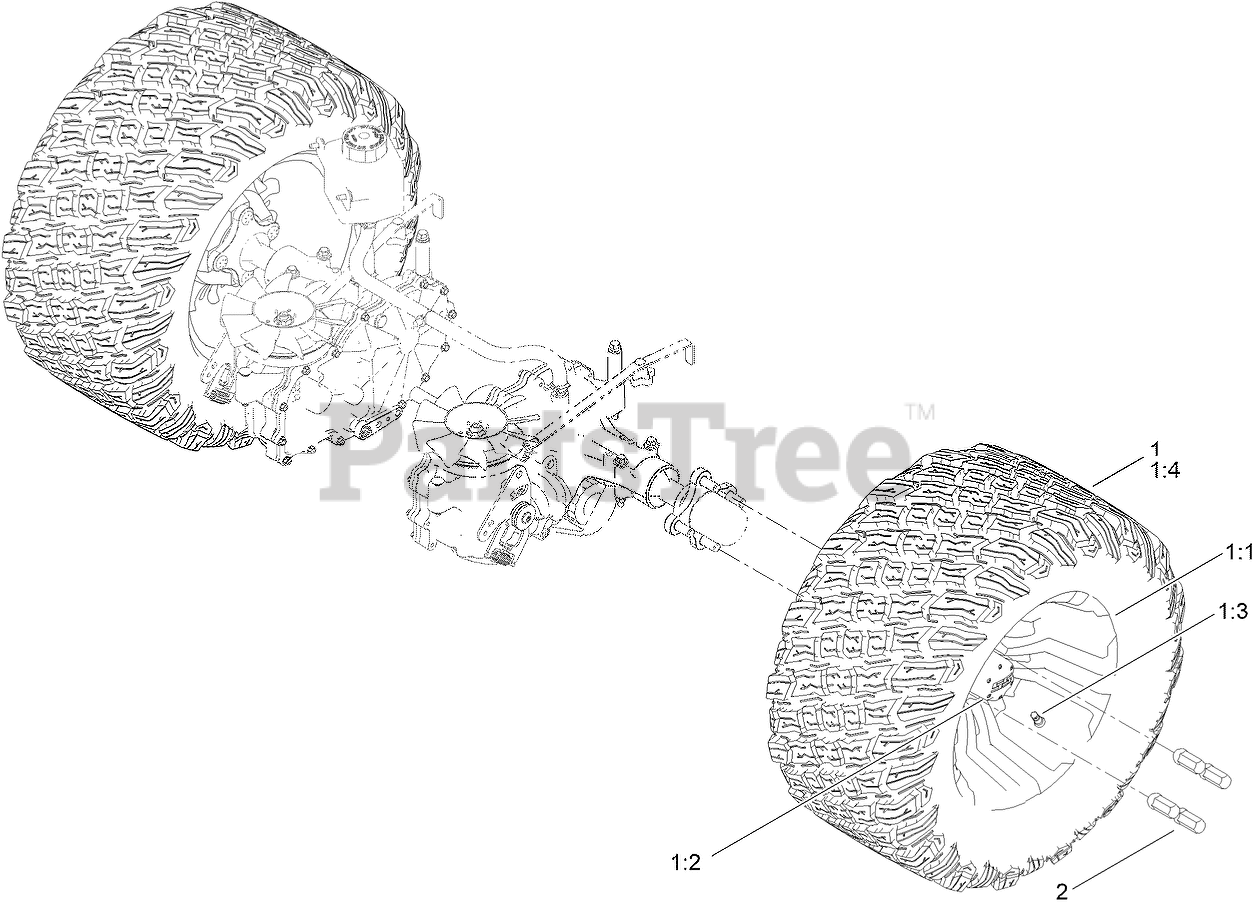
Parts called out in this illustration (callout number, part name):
1	TIRE ASM
1:2	CAP-WHEEL
1:3	STEM-VALVE
2	NUT-LUG
